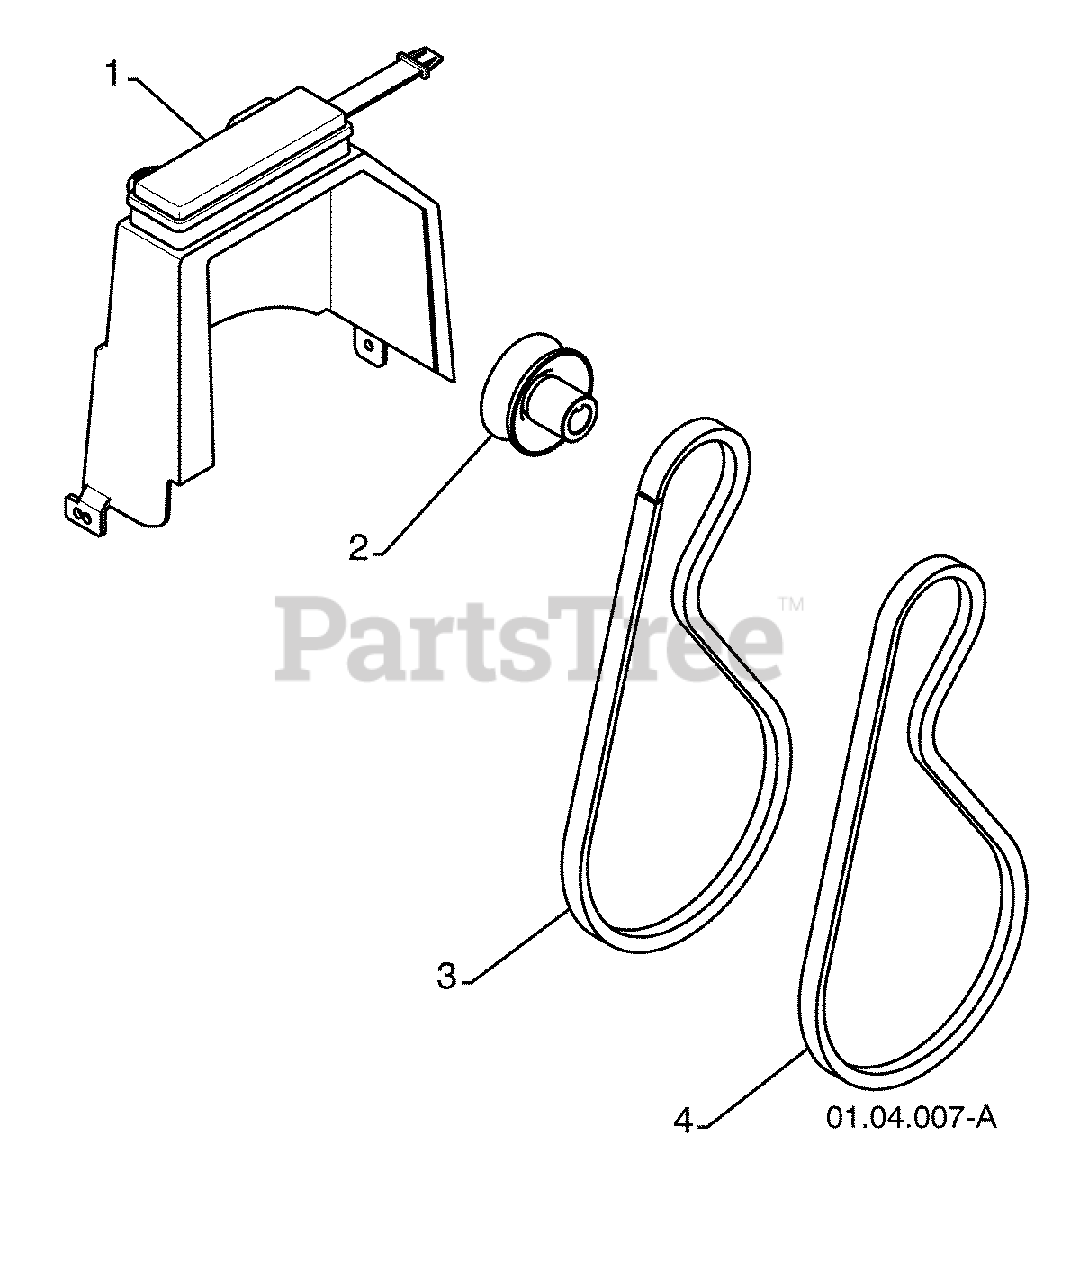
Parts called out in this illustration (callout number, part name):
1	COVER ASSEMBLY
2	PULLEY
3	TRACTION BELT
4	IMPELLER BELT
